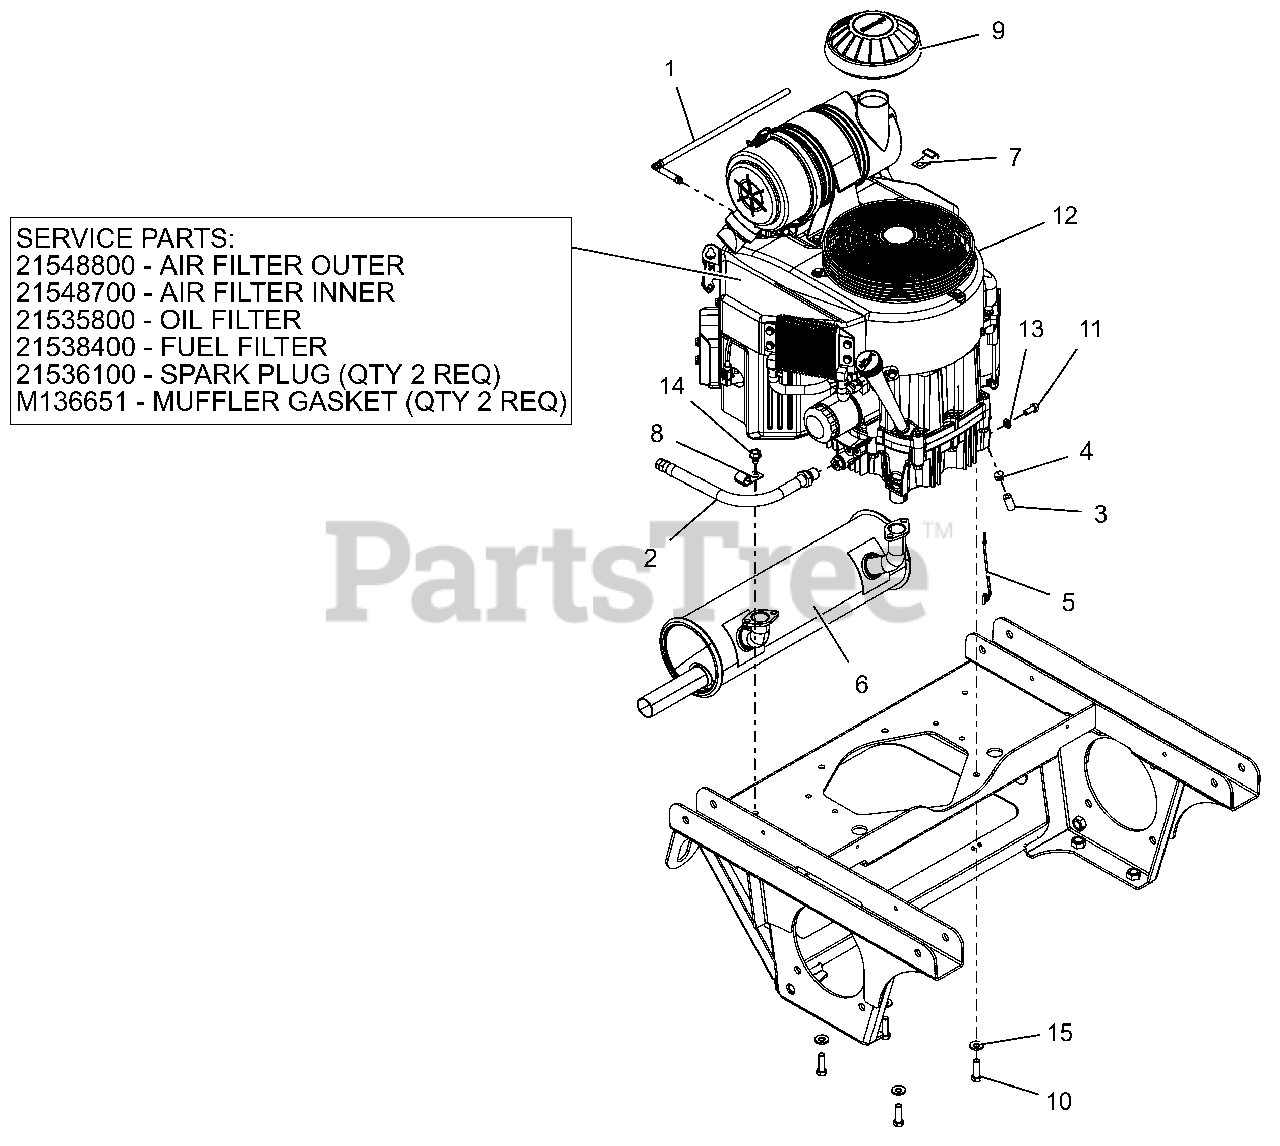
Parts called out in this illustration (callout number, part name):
1	ASM, VAPOR LINE
1	FILTER, OUTER
1	FILTER, INNER - KAW
1	FILTER,OIL - KAW
1	FUEL FILTER - KAWASAKI
1	PLUG, SPARK
1	GASKET, MUFFLER #
2	HOSE, OIL DRAIN
3	HOSE, .25 LOW-PERM BULK GAS
4	CLAMP, FUEL LINE
5	LEAD - STARTER SOLENOID
6	MUFFLER, 27-31 KAW
9	CAP, AIR CLEANER INTAKE (2")
10	BLT-HEX.38-16X1.25 G5YZ NYTORQ
11	@BLT-HEX M8-1.25X20 YWZC
12	ENGINE, KAWASAKI FX850
13	@WSHR-LK .31X.078 REG YWZC
14	@SCR-TAP .38-16X.50 HWH TR YWZ
15	WASHER, 3/8" SPRING DISC
